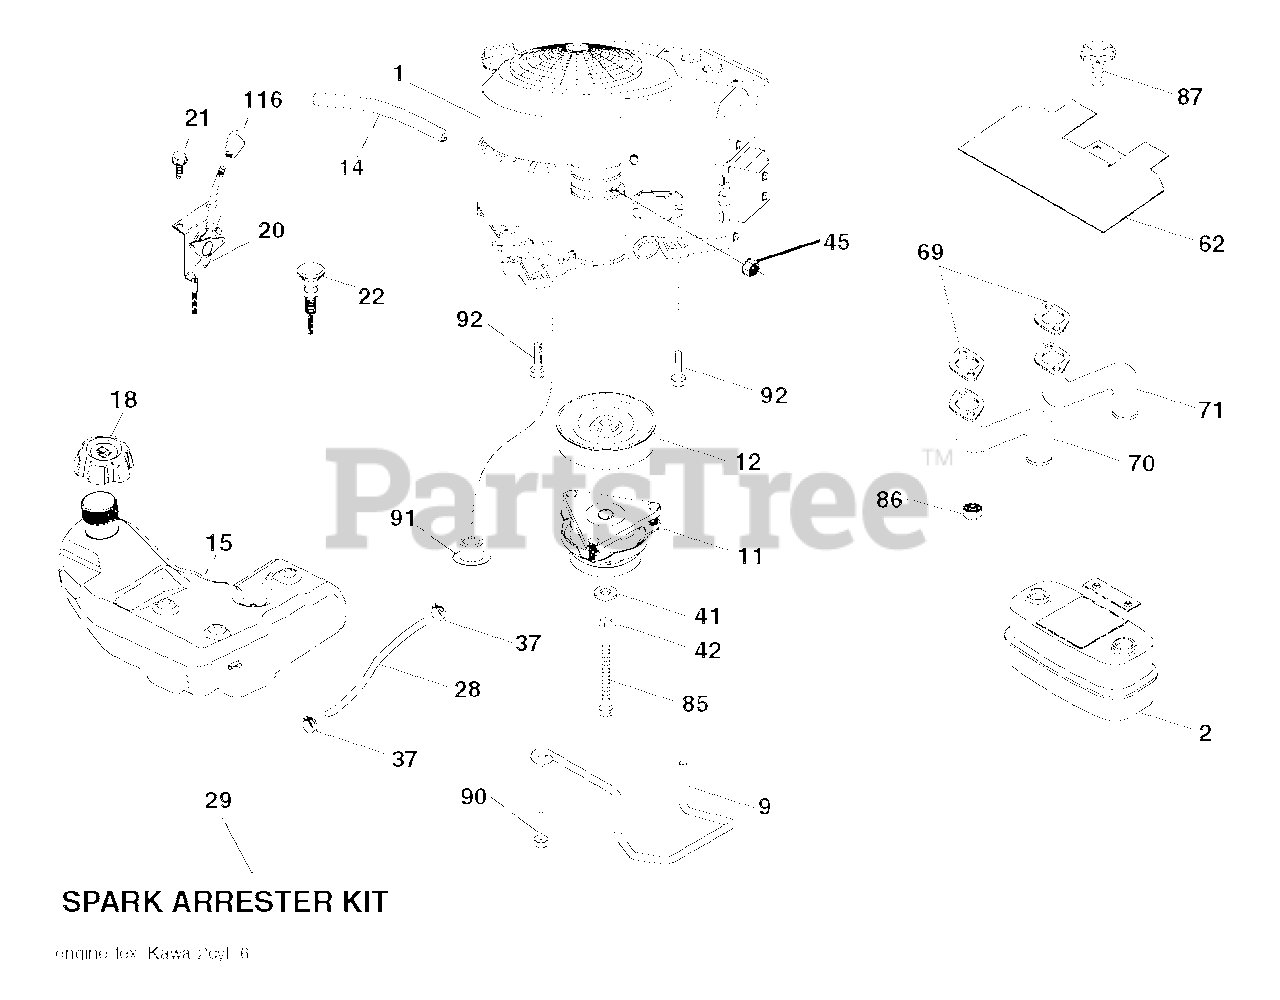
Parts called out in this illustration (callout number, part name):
2	MUFFLER.TWIN.CYL.LOW.TONE
9	KEEPER BELT ENGINE
11	CLUTCH ELECTRIC
12	PULLEY ENGINE
14	TUBE, DRAIN OIL ASM.
15	TANK.FUEL.4GAL
20	CONTROL.THROTTLE.PRO.
21	SCREW.#10 X 0.750.BOS (2 2)
22	CONTROL CHOKE
29	KIT.SPARK ARRESTOR(392390 B&S)
37	HOSE CLAMP
42	LOCKWASHER
45	NUT
62	SHIELD.HEAT.MUFFLER
70	TUBE.EXHAUST.LH.FR961/FR730
71	TUBE.EXHAUST.RH.FR961/FR730
85	BOLT HEX 7/16-20 X 3.75 GR. 5
86	NUT.HEX.FLANGE.TOPLOCK
87	BOLT.5/16-18UNCX1.W/SEMS.BLK
90	SCREW 3/8-16X1
91	BUSHING.1.375OD
92	SCREW 3/8-16X1
116	RP KNOB SOFT TOUCH
